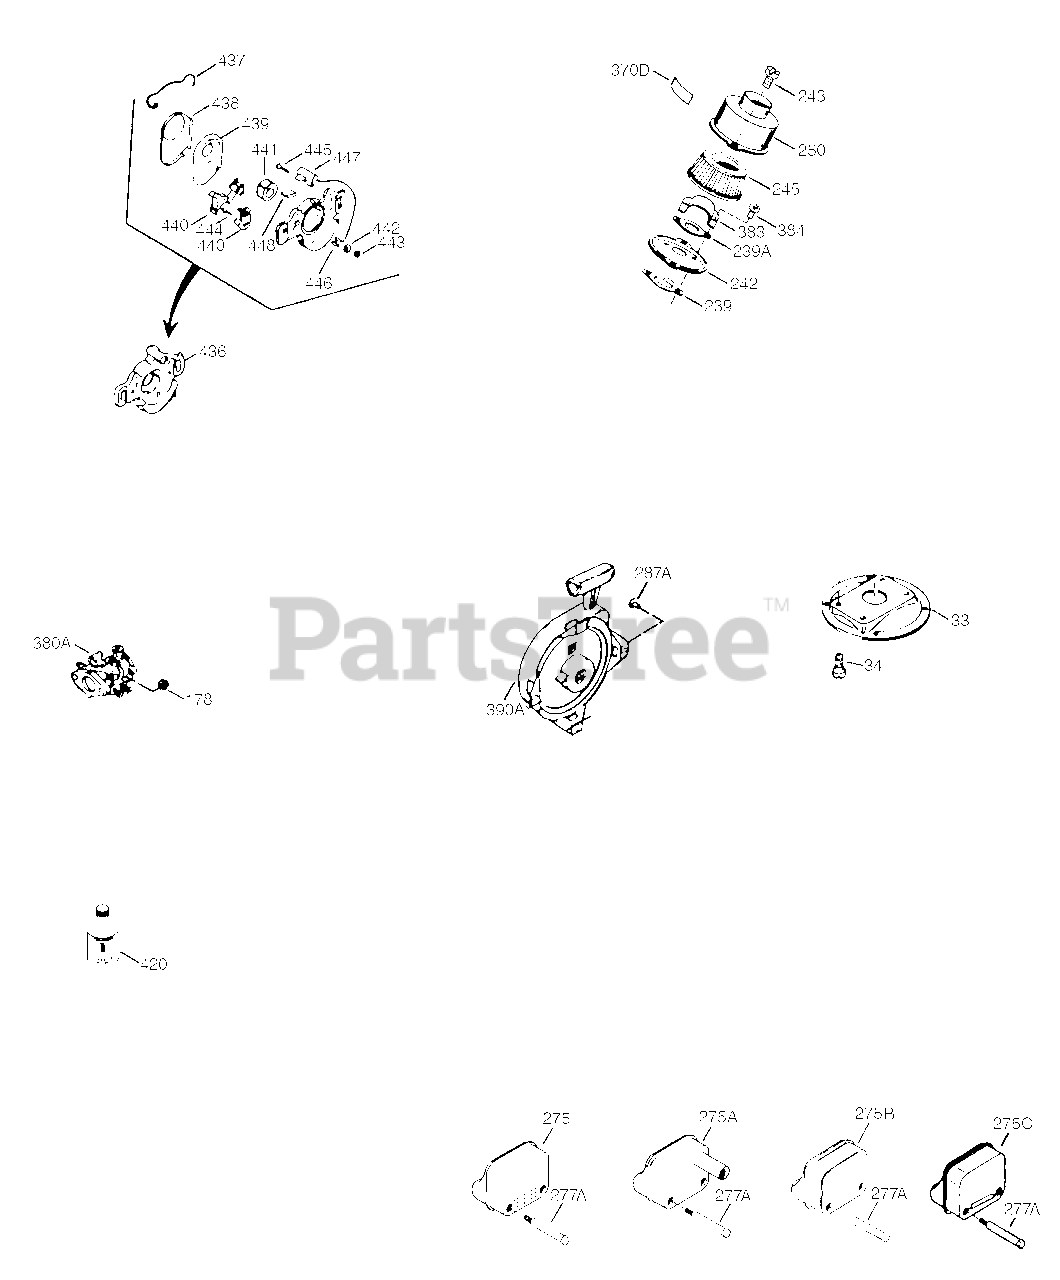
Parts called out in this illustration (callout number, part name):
130B	Screw, 1/4-20 x 1/2"
209	Screw, Torx T-25, 10-24 x 1/2"
211	Screw, Torx T-25, 10-32 x 5/8"
239	Air Cleaner Gasket
275	Muffler
277A	Screw, 1/4-20 x 2-3/4"
353A	Screw, Torx T-30, 1/4-20 x 3/4"
383	Spit Cup
420	2-Cycle Oil with Fuel Stabilizer - 8 oz.
900	Replacement S/B 710574, order from 71 -999
900	Replacement Engine - None
